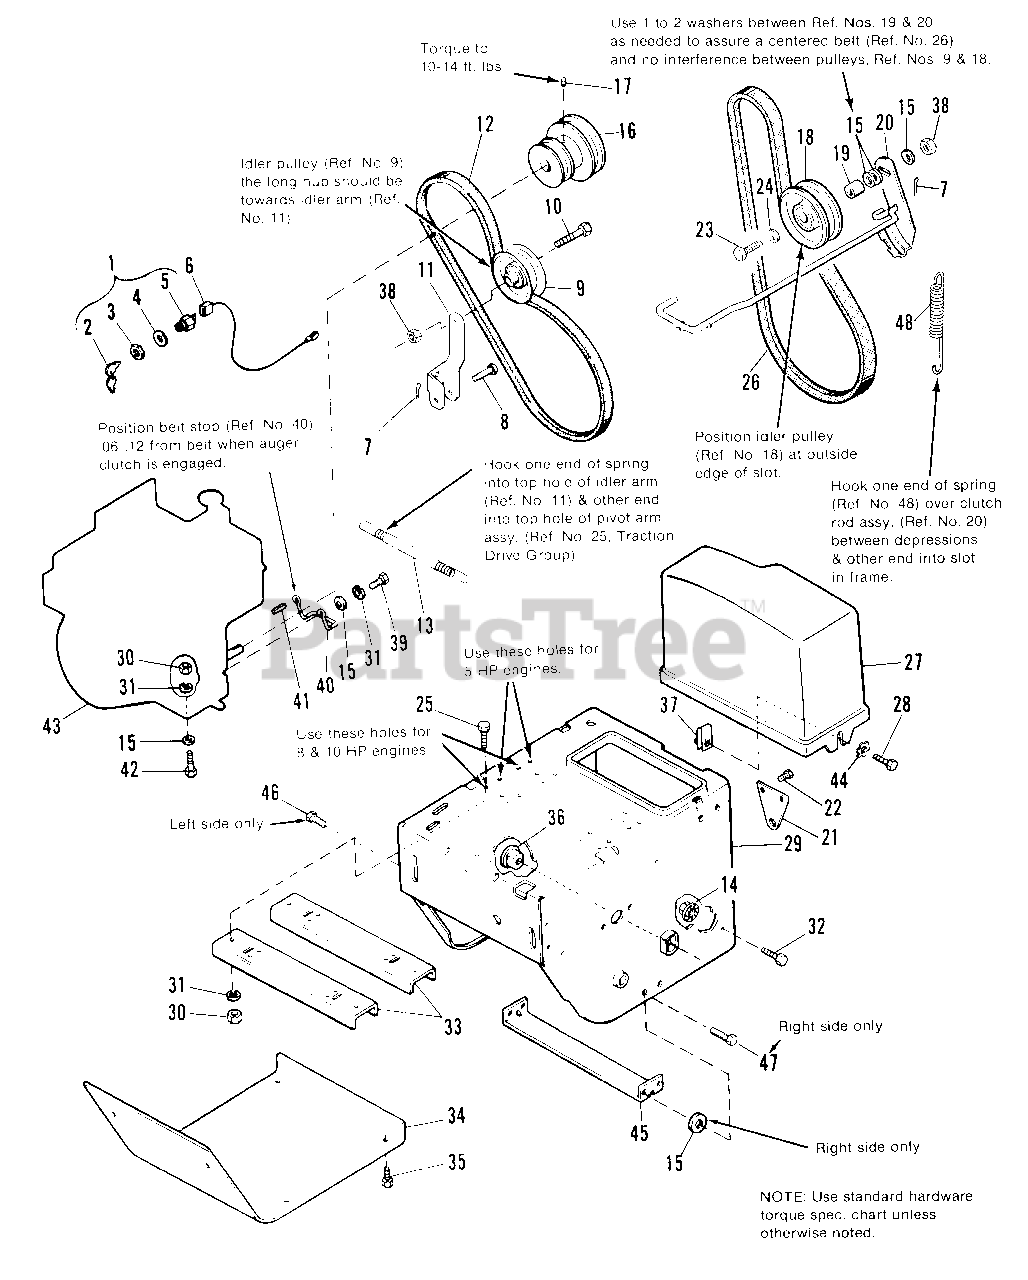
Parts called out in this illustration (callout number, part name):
1	SWITCH, Key (Inc. Ref. Nos. 2, 3, 4 & 5)
3	NUT, Hex, 5/8-32
4	LOCKWASHER, Int. 5/8
6	WIRE, Ground
7	PIN, Cotter, 1/8 x 3/4
8	PIN
9	PULLEY, Idler
10	CAPSCREW, Hex Hd., 3/8-16 x 1-1/2
11	ARM, Idler, Traction
12	BELT, Traction
13	SPRING, Idler
14	NUT, Hex, Whizlock 5/16-18
14	BELT STOP
15	WASHER, Flat, 5/16 (Qty. 10 1691708)
16	PULLEY, Engine
17	SETSCREW, Socket Hd., 5/16-18 x 5/8
18	PULLEY ASSY.
20	CLUTCH ROD ASSY.
21	BRACKET, Clutch Pivot
22	SCREW, Taptite, 1/4-20 x 1/2
23	CAPSCREW, Hex Hd., 3/8-16 x 3/4
24	WASHER, Flat, 3/8
25	CAPSCREW, Hex Hd., 3/8-16 x 3/4
26	BELT, Auger Drive
27	GUARD, Belt
28	SCREW, Truss Hd., 5/16-18 x 3/4
29	FRAME, Main
30	NUT, Hex, 5/16-18
31	LOCKWASHER, 5/16
32	CAPSCREW, Whizlock 5/16-18 x 3/4
33	BRACKET, Engine Mounting
34	COVER, Bottom
35	SCREW, Tapttite, 1/4-20 x 3/8
36	BUSHING, Axle
37	NUT, Pal, 5/16-18
38	LOCKNUT, Jam, 3/8-16
39	CAPSCREW, Hex. Hd., 5/16-24 x 3/4
40	BELT STOP
41	KEY, 3/16 x 3/16 x 1-1/2
41	KEY, 1/4 x 1/4 x 1-1/2
42	CAPSCREW, Hex Hd., 5/16-18 x 1-3/4
42	CAPSCREW, Hex Head 5/16-18 x 2 G5
43	ENGINE, Tecumseh, 8 H.P., Electric Start ENGINE, Briggs & Stratton, 8 H.P., Manual Start
44	LOCKWASHER, Ext. Tooth, 5/16
45	SUPPORT, Tie Bar
46	SCREW, Taptite, 5/16-18 x 3/8 (left side only)
47	SCREW, Taptite, 5/16-18 x 3/4 (right side only)
48	SPRING, Brake
